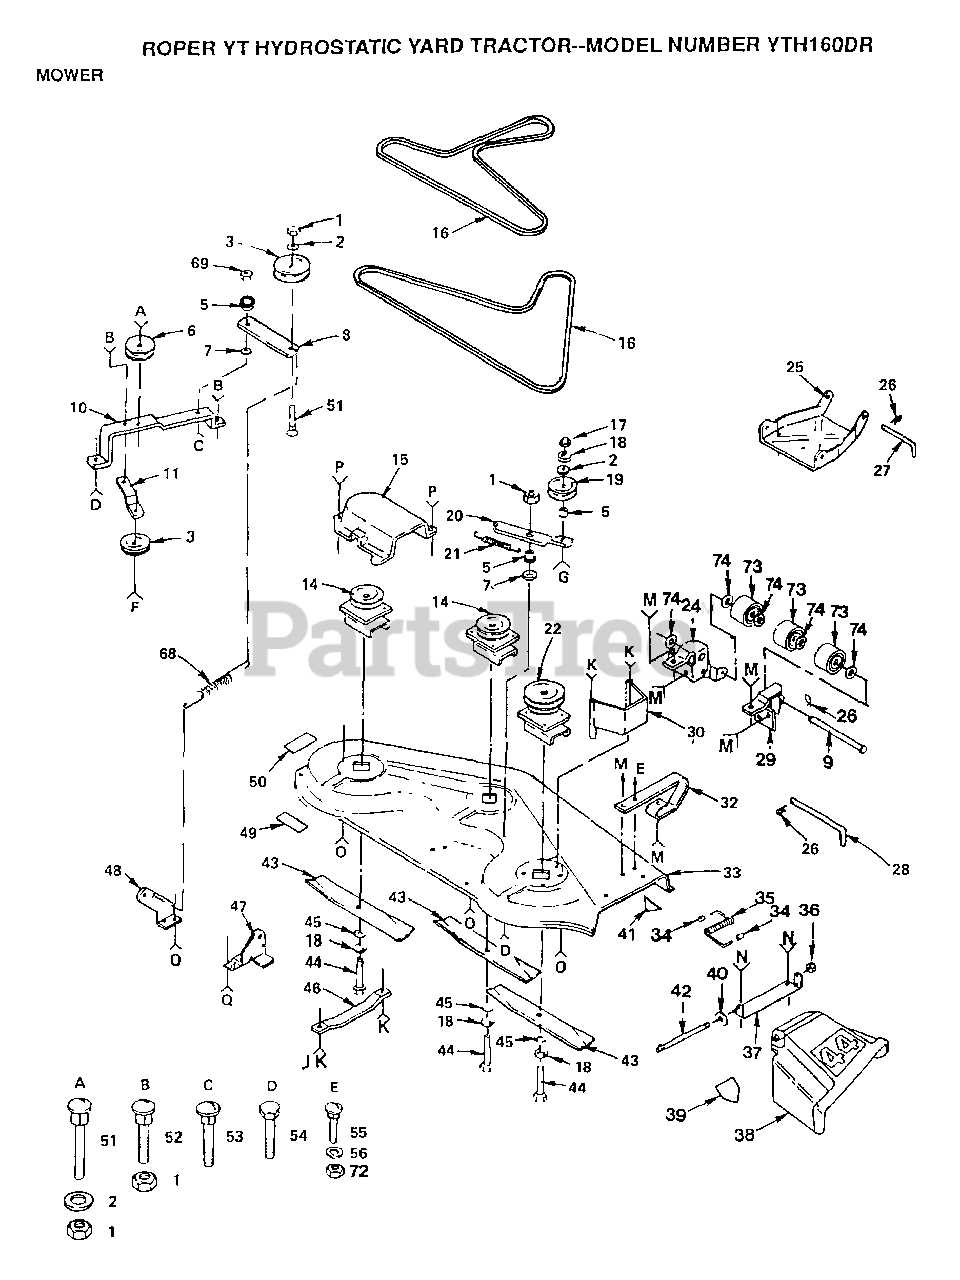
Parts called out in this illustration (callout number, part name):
2	WASHER
3	IDLER-FLAT T
5	SPACER RETAINER
6	IDLER-INSIDE T
7	"WASHER, WEAR LT"
8	ARM IDLER
9	PIVOT PIN T
10	"SUPPORT YT, BAR"
11	BRACE-IDLER YT
15	GUARD YT
16	BELT-V.79.1.MWR
17	NUT.HEX.3/8-16UNC
18	LOCKWASHER
19	IDLER.FLAT.GTV
20	ARM-IDLER YT
22	JACKSHAFT
24	BRACKET LH YTH
25	LINK.PARALLEL
26	SPRING.RETAINER
27	"ROD, FRT. PARAL T"
28	HINGE PIN T
29	BRACKET RH YTH
30	GUARD BELT HYT
34	CAP-SLEEVE LT
35	ROD-HINGE T
36	NUT PUSH M
38	DEFLECTOR SHIELD
39	DECAL WARNING
40	WASHER
42	ROD-HINGE T
44	BOLT.3/8-24X1-1/2
45	WASHER
46	RUNNER-LH M
49	DECAL HYT
50	DECAL-INST YT
51	BOLT
53	BOLT
55	BOLT
56	WASHER
68	"SPRING.EXT.8.5"""
69	LOCKNUT
73	ROLLER T
74	WASHER T
